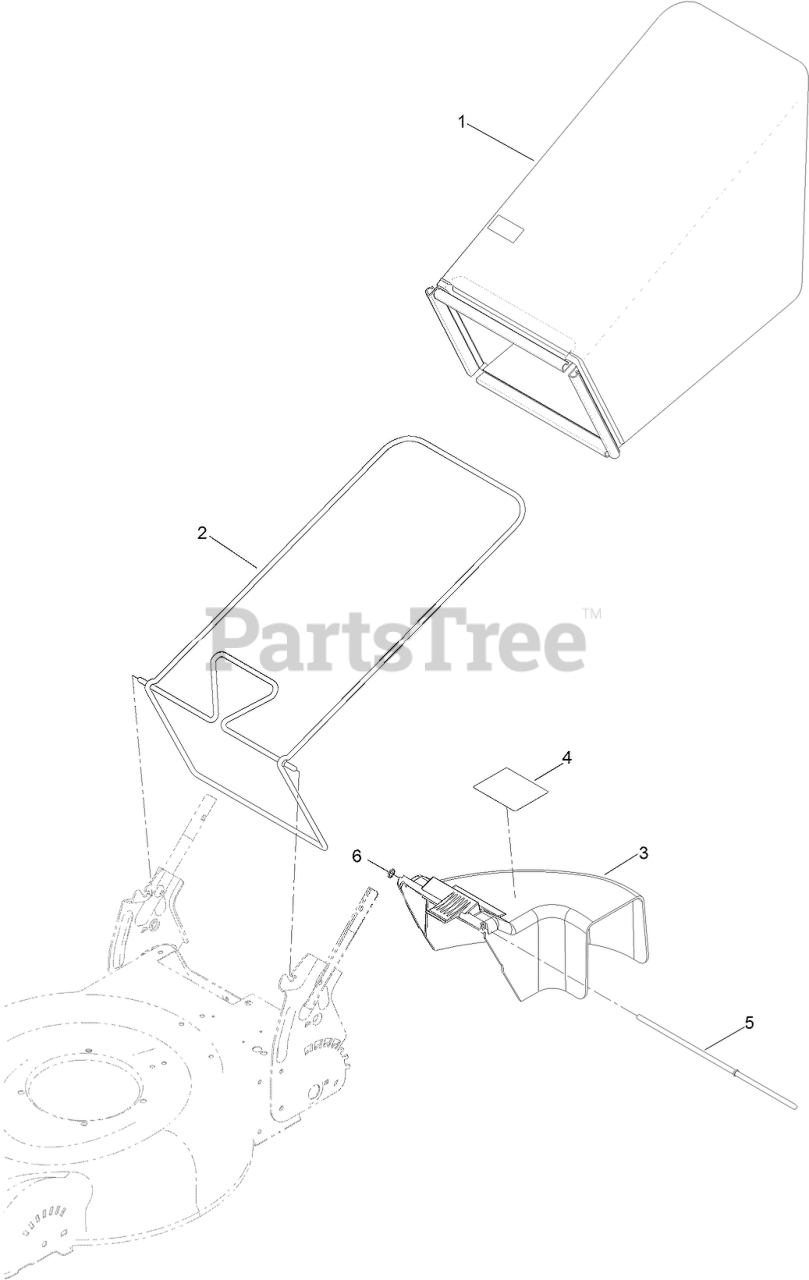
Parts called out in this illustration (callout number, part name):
1	GRASS BAG ASM
2	FRAME-BAG
3	REAR DEFLECTOR ASM
4	DECAL-WARNING
6	RING-RETAINING
